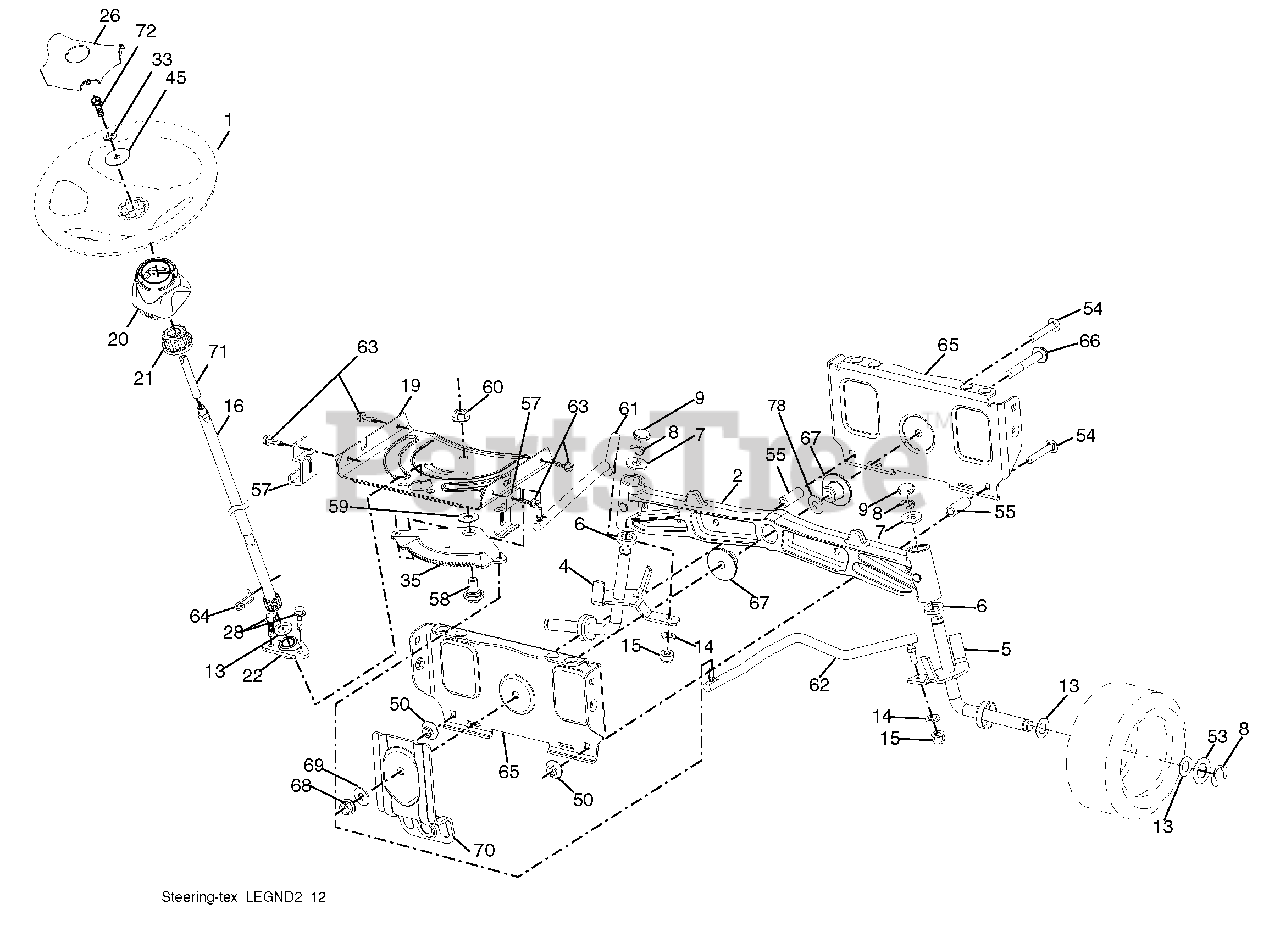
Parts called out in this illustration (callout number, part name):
1	Wheel, Steering
2	Axle Asm., Front
4	Spindle Asm., LH
5	Spindle Asm., RH
6	Bearing, Race Thrust Harden
7	Washer 25/32 x 1-5/8 x 16 Ga.
8	Ring, Clip #T5304-75
9	Cap, Spindle
13	Washer 25/32 x 1-1/4 x 16 Ga.
14	Washer Lock 3/8
15	Nut, Crown Lock 3/8-24 unf
16	Shaft Steering
19	Plate Steering
20	Boot, Steering
21	Adapter, Wheel Steering
22	Bushing, Strg. Blk
26	Insert, Wheel Steering
28	Screw 3/8-16 x 3/4
33	Washer Lock 5/16
35	Gear, Sector Plate
45	Washer 11/32 x 2-3/8 x 12 Ga.
50	Nut Lock Flg 3/8-16 unc
53	Washer Hardened .793 x 1.637 x .060
54	Bolt Hex HS 3/8-16 unc x 2-1/4
55	Spacer Brace Axle
57	Bracket Upstop
58	Bolt Shoulder Sector Pivot CFM
59	Washer Thrust Sector Steering
60	Nut Flange Lock 5/8-11
61	Draglink, LH
62	Draglink, RH
63	Screw 5/16-18 x 3/4
64	Retainer Clip Spring Steering
65	Brace Axle Front
66	Bolt Hex Fghd 7/16-14 x 3 Serr
67	Bushing PM Front Axle
68	Nut Lock Flange 7/16-14 Gr. 5
69	Washer 1.5 x .505 x .118
70	Bracket Deck Susp. Front
71	Shaft Ext. Steering
72	Bolt 5/16-18 x 4.5 Gr. 5
78	Washer Thrust .515 x .750 x .033
